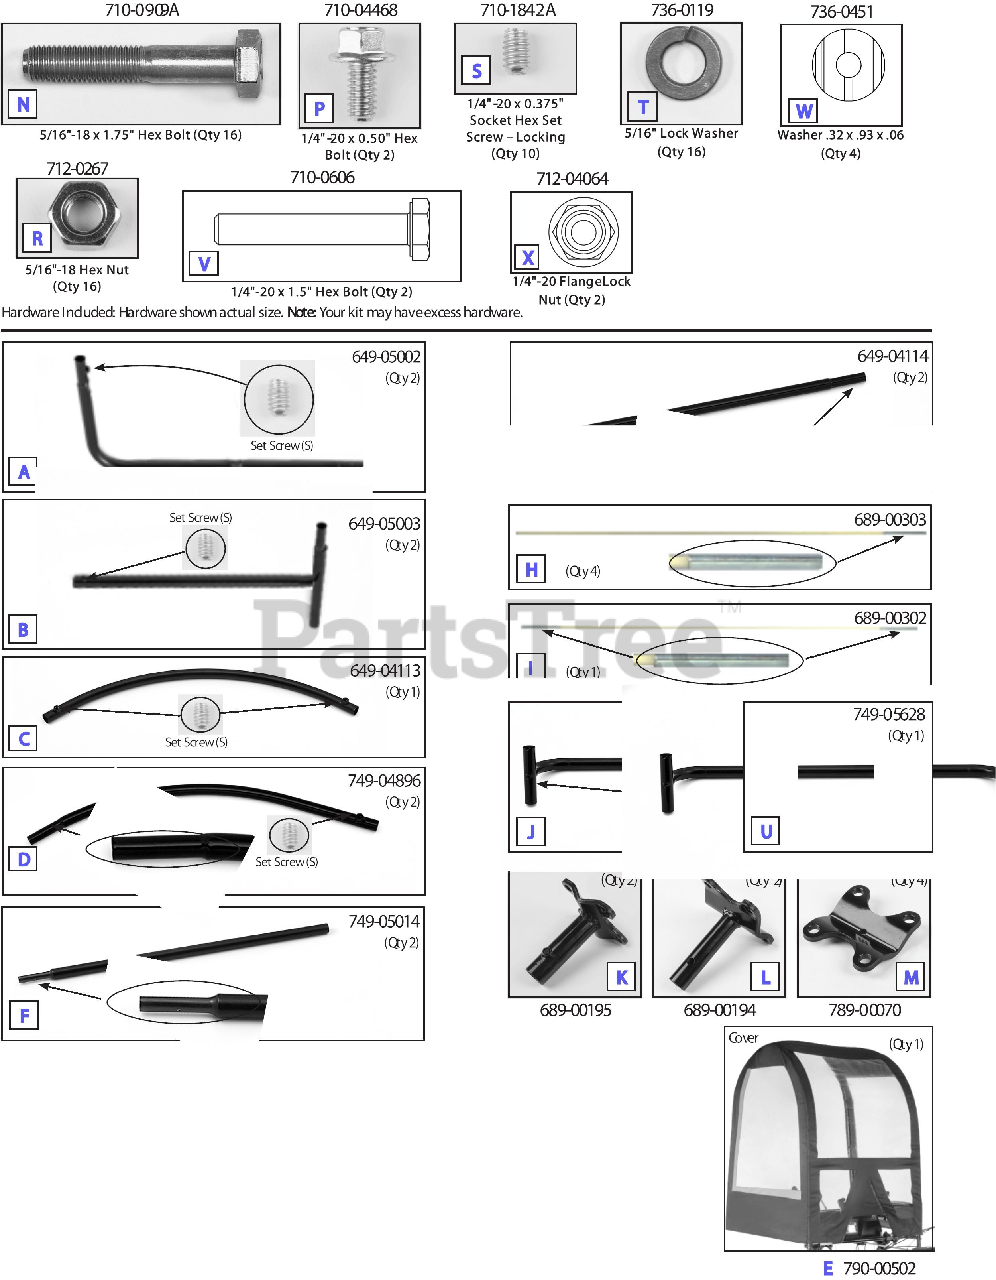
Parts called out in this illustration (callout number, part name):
N	Screw 5/16-18 X 1.750
P	Screw 1/4-20 X .50 Gr5
S	Screw 1/4-20 X .38
T	Lock Washer 5/16
W	Saddle Washer
R	Hex Nut 5/16-18
V	Screw 1/4-20 X 1.50 Gr.5
X	Flange Lock Nut
A	Back Side Rail Tube Assembly
B	Front Side Rail Tube Assembly
C	Arc Center Bar
D	Arc End Bar (Lh) & (Rh)
F	Front Vertical Tube
G	Upright Rear Pole
H	Single Rod Assembly
I	Double Rod Assembly
J	Crossbar
K	Female Tube/Clamp Assembly
L	Male Tube/Clamp Assembly
M	Clamp Plate
U	Crossbar Connector
E	Snow Cab Cover
